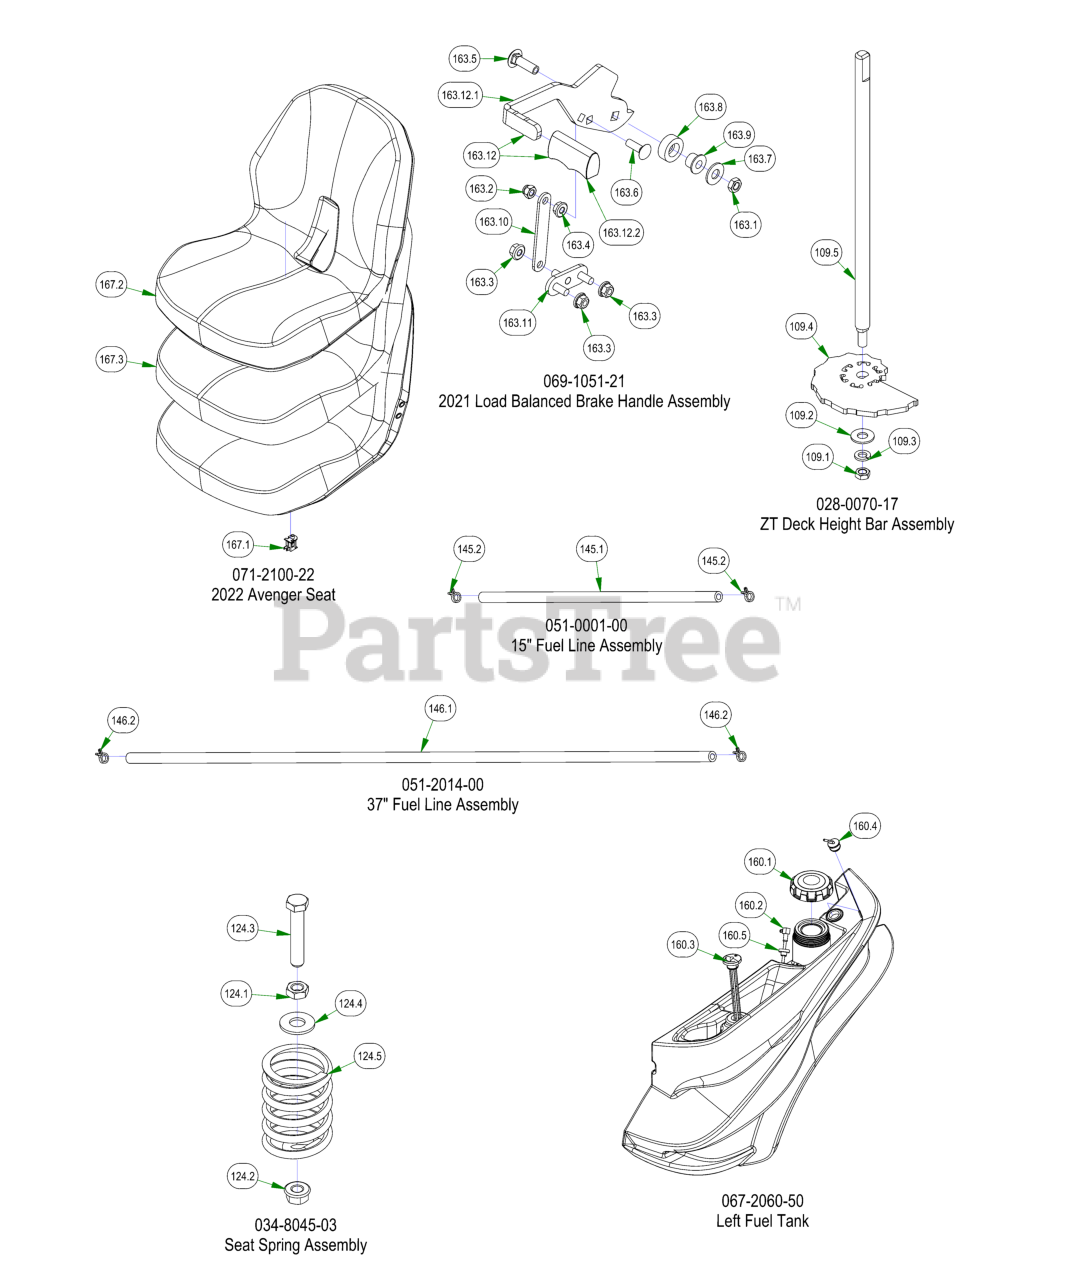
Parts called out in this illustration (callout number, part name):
83	1/4 USS FLAT WASHER (3/4 OD) ZINC
91	ZT Tire and Rim Assembly 22 x 11 - 10
109	ZT Deck Height Bar Assembly
109.1	3/8-24 HEX NUT ZINC YELLOW
109.2	3/8 FLAT WASHER USS (1" OD) ZINC
109.3	3/8 SPLIT LOCKWASHER ZINC
109.4	2017 MZ/ZT Cam Plate
109.5	2017 Deck Height Dial Rod ZT
124	Seat Spring Assembly
124.1	3/8-16 Half Jam Nut
124.2	3/8-16 HEX SERRATED FLANGE NUT HARD/ZINC
124.3	3/8-16 X 2 HEX CAP SCREW (GR.5) ZINC
124.4	3/8 FLAT WASHER USS (1" OD) ZINC
124.5	Seat Spring
145	15" Fuel Line Assembly
145.1	1/4 Fuel Line
145.2	1/4 Fuel Hose Clamp
146	37" Fuel Line Assembly
146.1	37" 1/4 Fuel Line
146.2	1/4 Fuel Hose Clamp
160	Left Fuel Tank
160.3	Fuel Gauge w/Grommet
160.4	Rollover Valve W/Grommet
160.5	Pick-Up Grommet
163	2021 Load Balanced Brake Handle Assembly
163.1	3/8-16 HEX JAM 2-WAY REVERSIBLE CENTER LOCKNUT ZINC
163.2	5/16-18 NYLON INSERT CAP LOCKNUT ZINC (BLK CAP)
163.3	5/16-18 NYLON INSERT FLANGE LOCKNUT ZINC
163.4	5/16-18 HEX SERRATED FLANGE NUT HARD/ZINC
163.5	3/8-16 X 1-1/4 CARRIAGE BOLT ZINC
163.6	5/16-18 X 1 CARRIAGE BOLT (GR.8) ZINC
163.7	3/8 FLAT WASHER USS (1" OD) ZINC
163.8	2015 Brake Lever Spacer
163.9	.377 ID X .625 OD X .500 HGT X .880 FLNG DIA X .060 FLNG THK
163.10	Brake Cable Extension Plate
163.11	Brake Load Balancer Lower Weldment
163.12	Load Balanced Brake Handle with Grip
163.12.1	Switch Relocation Brake Handle
163.12.2	Brake Handle Rubber
167	2022 Avenger Seat
167.1	Seat Switch
167.2	Avenger Seat Cover
167.3	Water Proofing Protection
